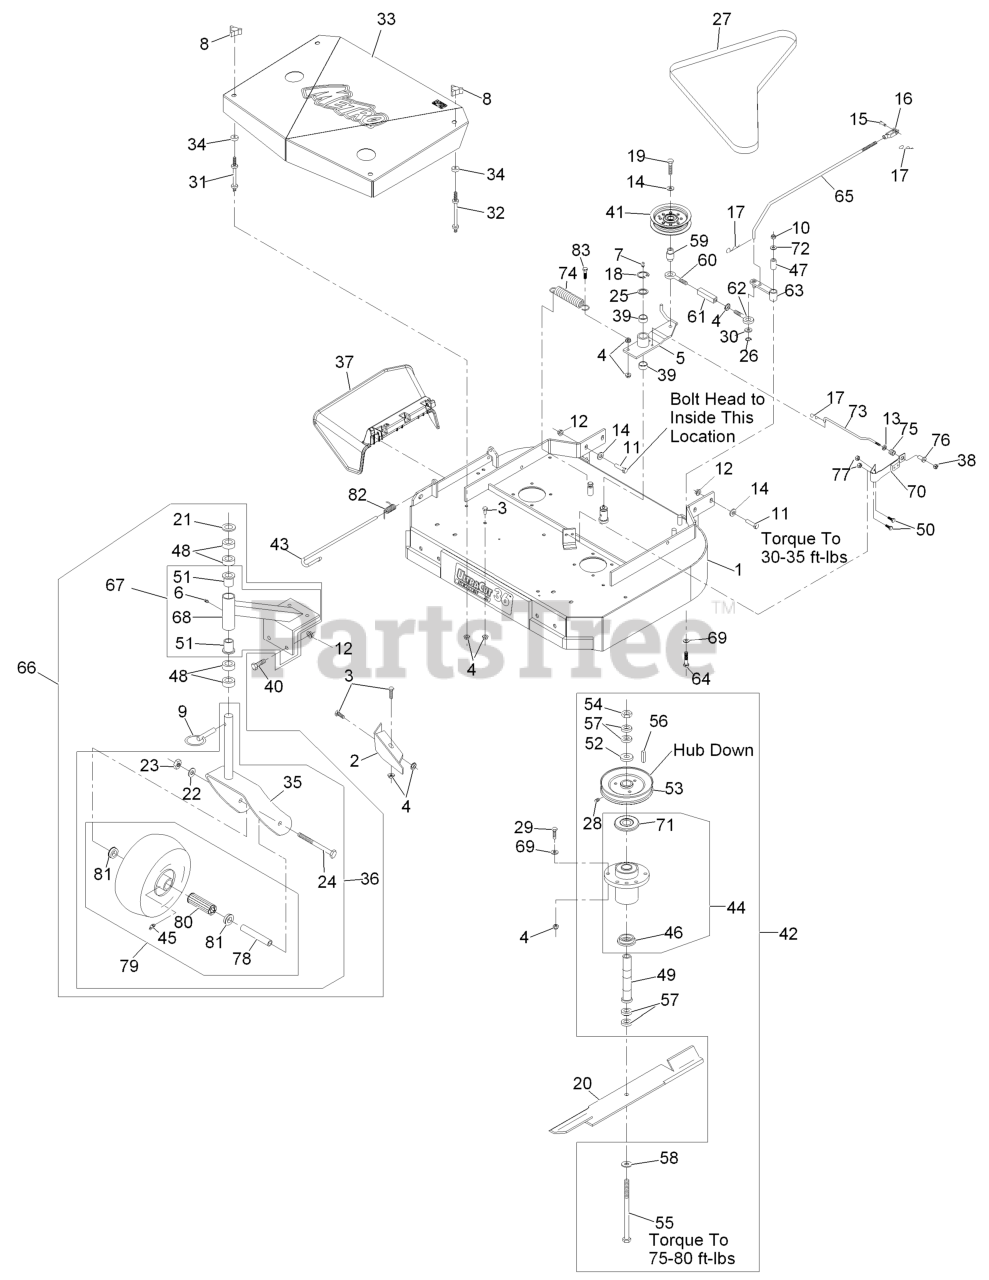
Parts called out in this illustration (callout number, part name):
1	ASM,DECK 36 RIGID
2	BAFFLE-DOGLEG
3	SCREW-HH
5	IDLER ARM ASM
6	FITTING-GREASE
7	FITTING-GREASE
8	KNOB-3 PRONG
10	NUT-LOCK, NI
11	SCREW-HH
12	NUT-HHF, WHIZ
13	RING-PUSH ON
14	WASHER-BELLEVILLE
15	PIN-CLEVIS
16	YOKE-ADJUSTABLE
17	PIN-COTTER
18	RING-RETAINING, EXT
19	SCREW-HH
21	WASHER-FLAT
22	WASHER-LOCK
23	NUT-HH
24	SCREW-HH
25	WASHER-SPINDLE
26	RING-RETAINING, EXT
27	BELT,BLADE METRO 36
28	SETSCREW
29	SCREW-HH
30	WASHER-PLAIN
31	STUD-SHIELD, BELT (SHORT)
32	STUD-SHIELD, BELT (LONG)
33	ASM,SHIELD W/DECALS 36 ME
36	ASM,CASTER/WHEEL
37	CHUTE DEFLECTOR XRK M056
38	NUT-LOCK, NI
39	SLEEVE-BEARING
40	SCREW-HH
42	ASM, CUTTER HOUSING OUTER
43	PIN-CHUTE
44	KIT, CUTTER HOUSING
45	FITTING-GREASE
46	SPACER-GUARD, BOTTOM
47	TUBE-PIVOT
48	SPACER-CASTER
49	TUBE-SPINDLE, SHORT
50	SCREW-HH
51	BEARING-FLANGED
52	WASHER-RETAINER, SHEAVE
54	NUT-HEX
55	SCREW-CAP, HH
58	WASHER-SPRING
59	BUSHING-ENGAGEMENT
60	EYEBOLT-THREAD, LH
61	BODY-TURNBUCKLE
62	EYEBOLT-THREAD, RH
63	ARM-ASSIST, 32/36
64	SCREW-HH
65	ARM-ASSIST, LINKAGE
66	ASM,CASTER/MOUNT
67	SUPPORT ASM
69	WASHER-SPRING
70	PAD AND SPRING ASM
71	GUARD-BEARING, TOP
72	WASHER-FLAT
73	ROD-BRAKE
74	SPRING-EXTENSION
75	SPRING-COMPRESSION
76	SPACER-FLANGED
77	NUT-LOCK, NI
79	KIT, SP CASTER WHEEL REPL
80	BEARING
81	BUSHING
82	SPRING, TORSION
83	SCREW-HH, SPECIAL
